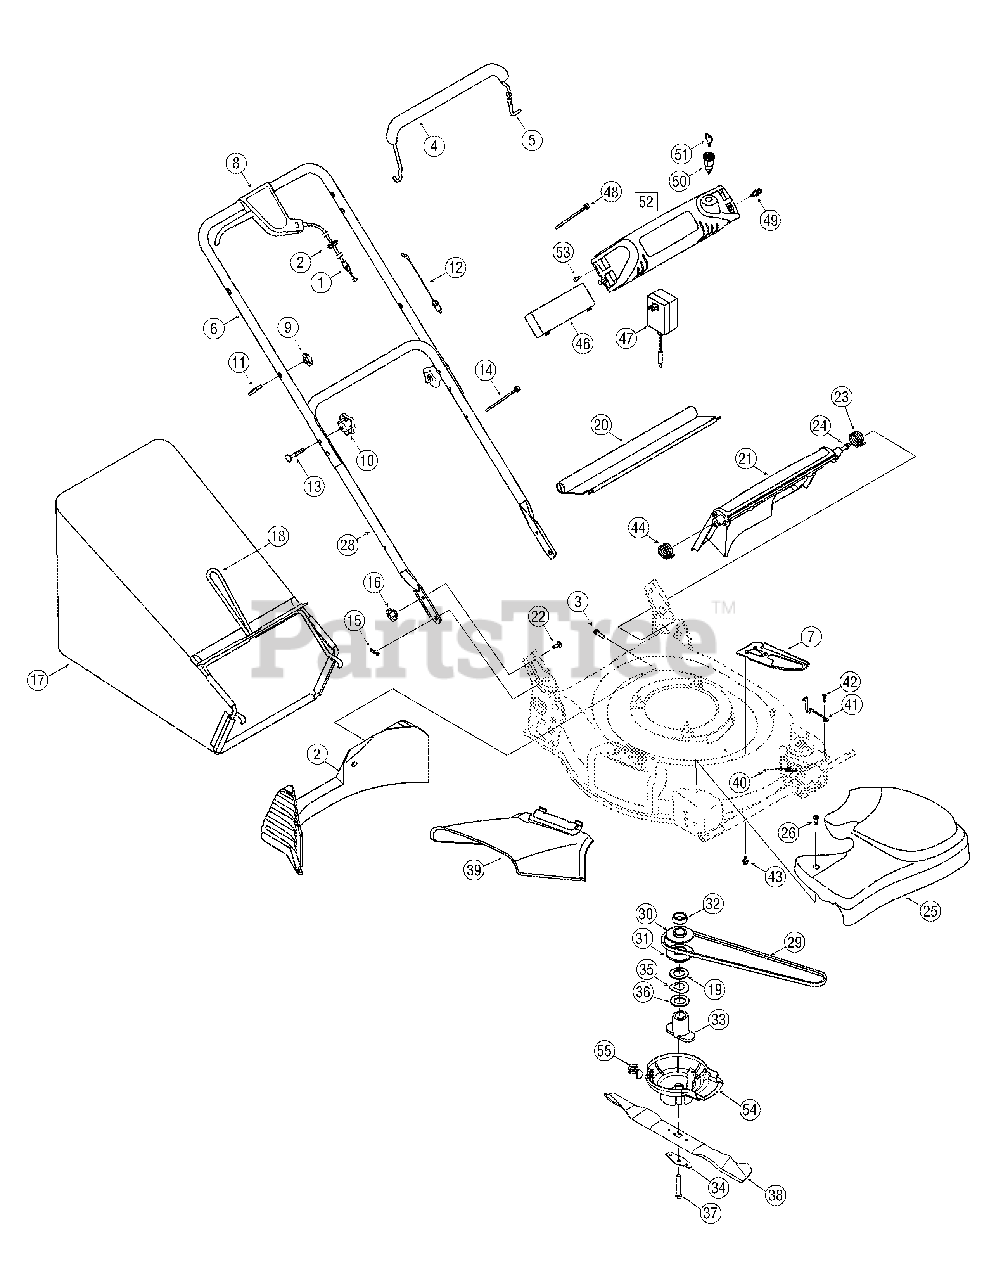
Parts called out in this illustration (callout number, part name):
1	Drive Cable
2	Rear Baffle 21" Rear Discharge
3	Hex Lock Screw 1/4-15 x 1.0
4	Bail Cover - Black
4	Bail Cover - Red
8	Control Lever Ass'y
10	Knob - Star 5/16-18
11	Rope Guide Bolt
12	Control Cable 37.25" Lg.
13	Carriage Bolt 5/16-18 x 2.0
14	Cable Tie
15	Int. Cotter Pin .072 x 1.13" Lg.
16	Wing Nut
17	Grass Bag -Generic
19	Sleeve Spacer 25 mm x 1.275 x .375
20	Trail Shield
21	Rear Discharge Door
22	Carriage Bolt 1/4-10 x .75
23	Torsion Spring LH
25	Transmission Cover (Grey)
25	Transmission Cover (Black)
26	Shoulder Screw #12-24
29	V-Belt
30	Upper Pulley Half 25mm x 2.62
31	Lower Pulley Half 25mm x 2.62
32	Sleeve Spacer 25 mm ID x 1.375 x .620
32	Sleeve Spacer 25 mm ID x 1.375 x .375
33	Blade Adapter
34	Blade Bell Support
35	Space Washer
37	Hex Bolt 3/8-24 x 2.5" Lg.
38	21" Mulching Blade
39	Chute Deflector
40	Extension Spring
41	Belt Keeper Wire
43	Screw 1/4-14 x 0.625
44	Torsion Spring RH
46	12V Battery
47	Battery Charger
48	Cable Tie
49	Rivet
50	Key Switch
51	Key
52	Electric Starter Harness Ass'y
53	Screw, #10-16 x .750
54	Engine Baffle
